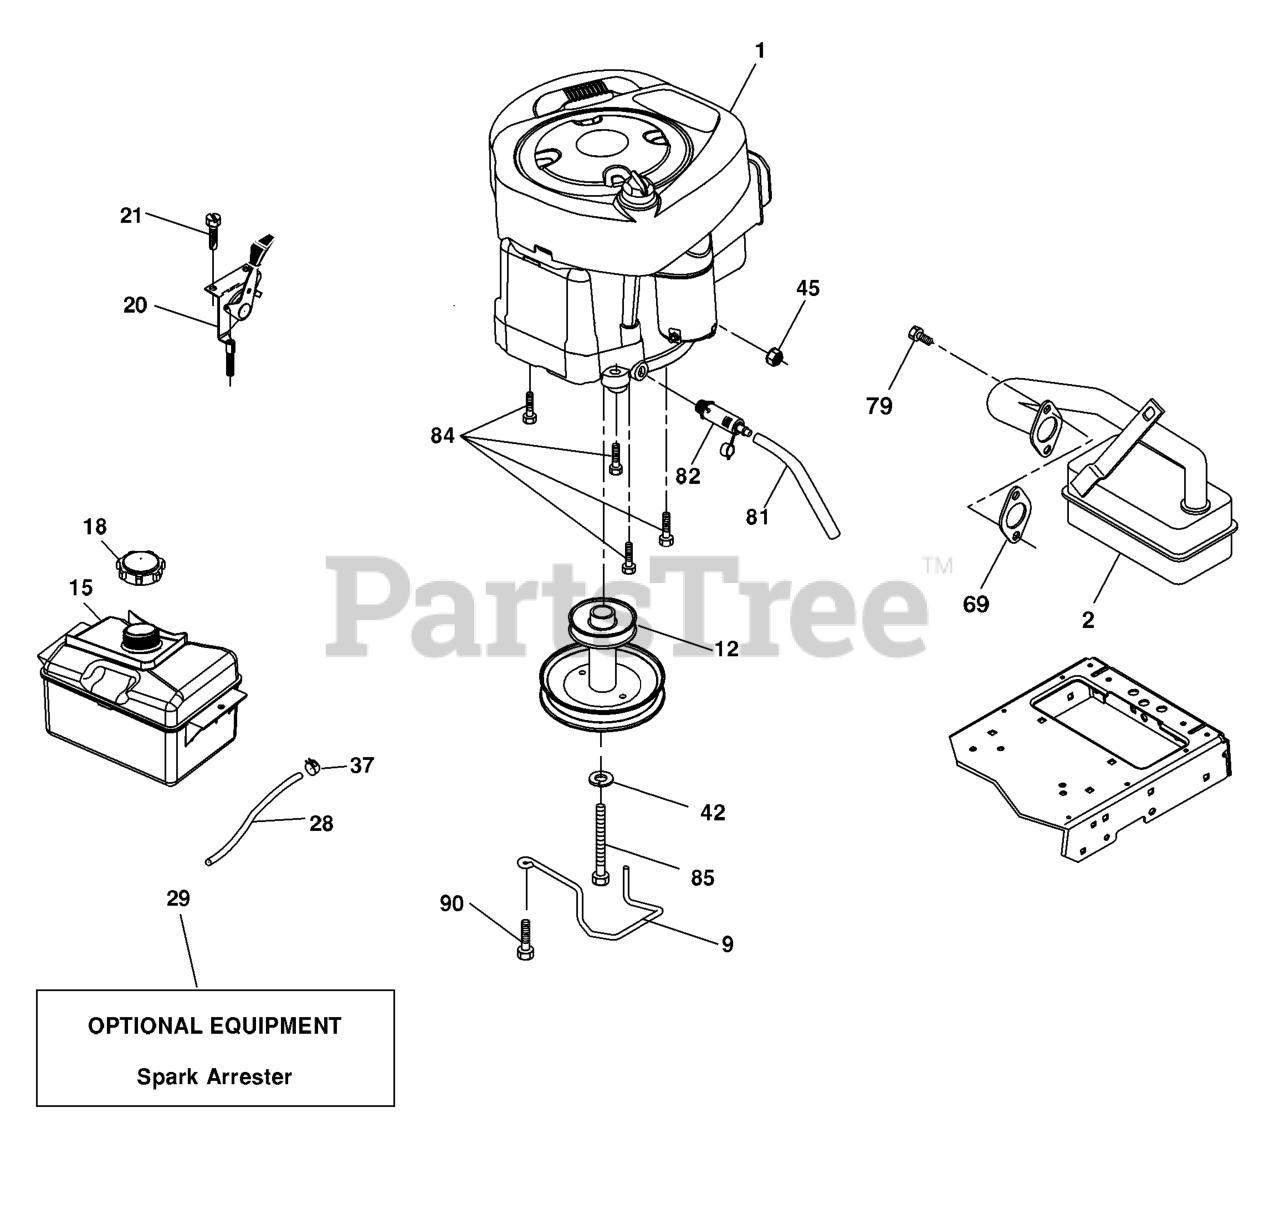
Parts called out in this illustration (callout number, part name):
2	MUFFLER.LT.BRIGGS.14HP.IC/OHV
9	KEEPER.BELT.ENGINE.4.2
12	PULLY ENGINE
15	TANK.ASM.FUEL.FR.2.5GA.
18	FUEL CAP
20	CONTROL.TH/CK.COBRA.KO
21	SCREW
28	LINE.FUEL.20"FRONT.EMI
29	KIT.SPARK ARRESTOR 794945 B&S
37	HOSE CLAMP
42	LOCKWASHER
45	NUT
69	REPL BY 532 27 22-93
79	SCREW.SOCKET HD.5/16-1
81	TUBE, DRAIN OIL ASM.
82	PLUG DRAIN OIL EASY
84	SCREW.3/8-16
85	BOLT HEX 7/16-20X4-1/4"
90	SCREW 3/8-16X1
